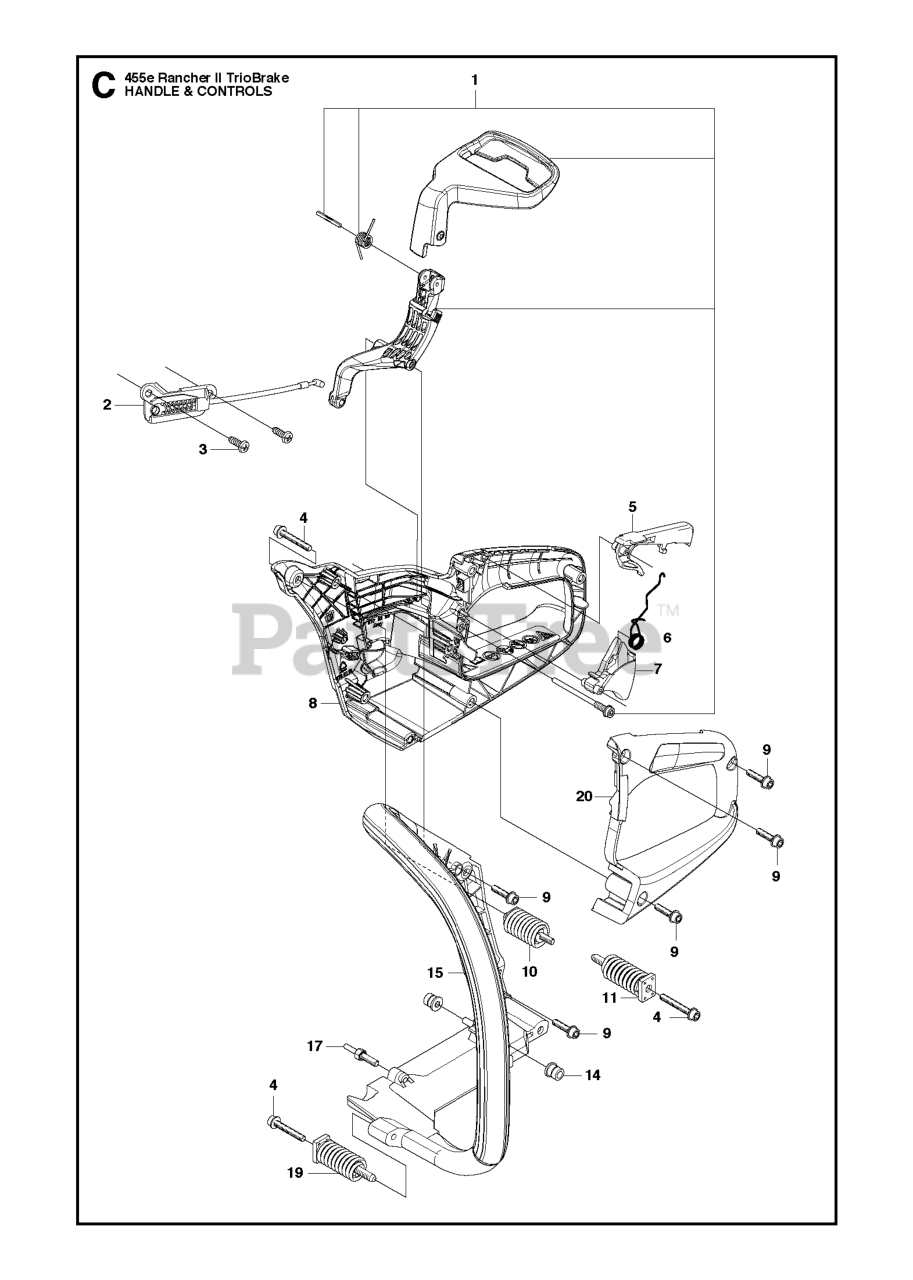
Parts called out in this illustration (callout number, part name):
5	THROTTLE LOCK
7	THROTTLE TRIGGER
8	REAR HANDLE
10	VIBRATIONS ABSORBER
11	VIBRATION ABSORBER
14	MOVEMENT LIMITER
15	FRONT HANDLE
20	CAP - LEFT SIDE HANDLE
